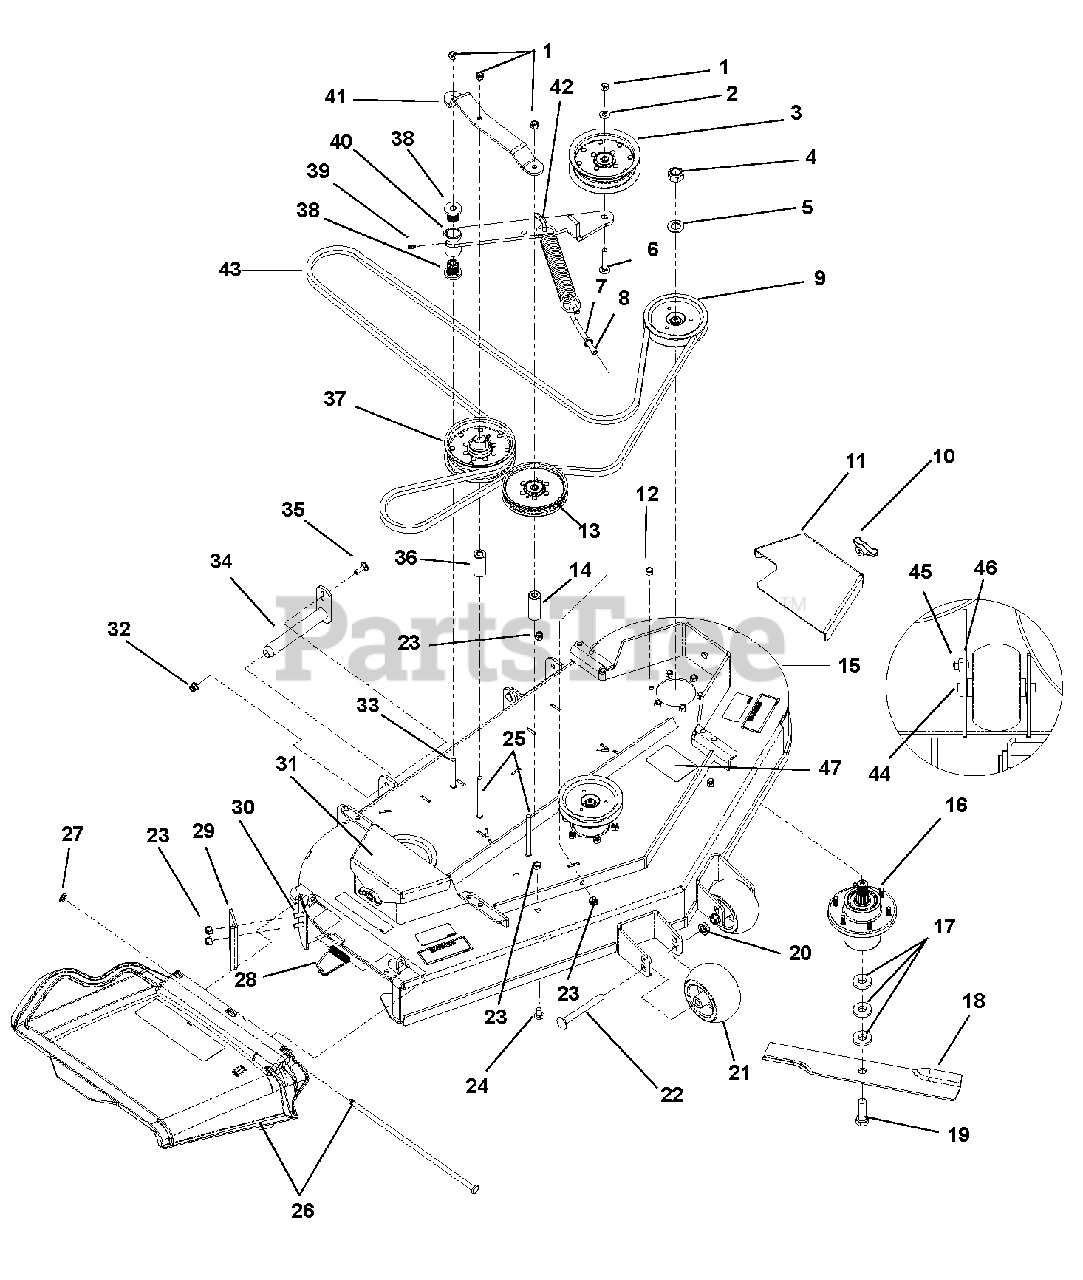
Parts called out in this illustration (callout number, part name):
1	NUT, 3/8 LOCK
2	WASHER, .406X.812X.065
3	PULLEY, FLAT 5.0 X.38 W/BRG
4	LOCKNUT, 3/4-16 CROWN C
5	WASHER, .75X1.3125X .113
6	BOLT, 3/8-16X2.25 CRG 5 Y
7	LOCKNUT, 3/8-16 WHIZ Y
8	J-BOLT, 3/8-16 X 4.00 Y
9	PULLEY, SPLINE SPINDLE LSE
10	KNOB, LOCKING
11	WELDMENT, BELT COVER LH 52
12	NUT, 3/8-16 STD HEX GR5 Y
13	PULLEY, FLAT 5.00 X .375 W/BRG
14	SPACER, .437 X 1.00 X 2.50 SMLS
15	ASSY, 52 EVERRIDE DECK W/ DECALS
16	ASSY, SPINDLE HOUSING
17	WASHER, BLADE
18	BLADE, 18.000 x .80 LIFT
19	BOLT, 5/8-11 X 2.00 HEX 8 Y
20	LOCKNUT 1/2 W/ FLANGE
21	WHEEL, GAGE
22	BOLT, 1/2-13 X 4.50 CRG 5 Y
23	LOCKNUT, 3/8-16 NYLOC Y
24	BOLT, 3/8-16 X 3/4 CAR GR5 LNNK
25	BOLT, CAR 3/8-16 X 5.00
26	CHUTE DISCHARGE ASST #
27	RETAINER #
28	SPRING, DISCHARGE CHUTE
29	PLATE, EXTENDER 48" HYDRO
30	BOLT, 3/8-16 X 1.00 CRG 5 SN Y
31	WELDMENT, BELT COVER rRH 52
32	LOCKNUT, FL,ISO7043,M8X1.25
33	BOLT, 3/8-16X3.50 CRG 5 Y
34	PIN, WELDED
35	BOLT, RH, SQNECK, JDS137, M8X1.25X
36	SPACER, .437 X 1.00 X 2.25 SMLS
37	PULLEY, FLAT 5.25 X .375 W/ BRG
38	BRG, FLG M1 X M25 X M27 FLUTED
39	FTG, 1/4-28 STRGT GREASE ZERK
40	ARM, IDLER
41	STRAP, IDLER PULLEY
42	SPRING, DECK IDLER
44	PIVOT, RETAINER WELD
45	NUT-1/4" FLANGE PREVAILING TOR
46	BOLT, 1/4-20 X .750 CRG 5 Y
47	DECAL, BELT PATH
